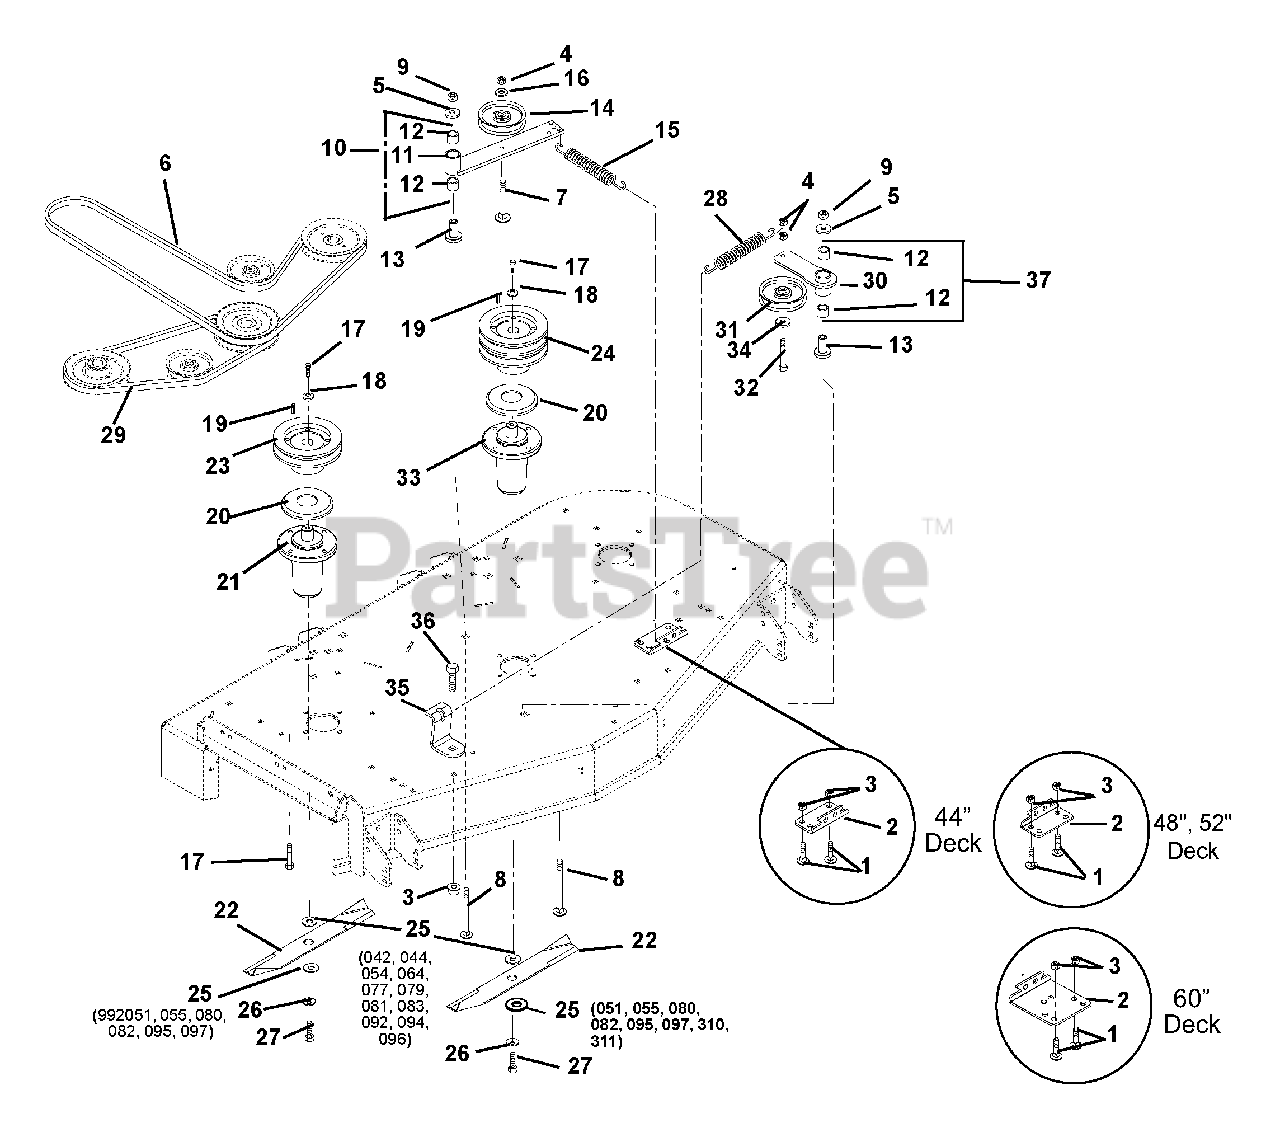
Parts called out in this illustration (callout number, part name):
1	Bolt, Round Head Square Neck .38-16 x .75 Grade 5
2	Bracket, Spring
3	Nut, Locking Top Flange .38-16
4	Nut, Locking Center .38-16
5	Washer, Flat Steel .531 x 1.25 x .10
6	V-Belt, B-Section 51.50 x .625
6	V-Belt, B-Section 55.75 x .625
6	V-Belt, B-Section 48.80 x .625
7	Bolt-Round Head Square Neck .38-16 x 2.75 Grade 5
8	Bolt, Round Head Square Neck .50-13 x 3.50 Grade 5
9	Nut, Locking Top Flange .50-13
10	Assembly, Idler Pivot Arm
11	Weldment, Idler Pivot Arm
12	Bearing, 1.00 x 1.12 x .75
13	Bearing, Pedestal Powdered Metal
14	Idler, Flat 4.00 x .38 (2.00 W)
15	Spring, Extension
16	Washer, Flat Steel .375 x 1.125 x .065
17	Bolt, Hex .38-16 x 1.00 EP30 Grade 8
18	Washer, Flat Steel .406 x 1.50 x .245
19	Key, Square .25 x .25 x 1.00 RC 40-50
20	Slinger, Dust
21	Assembly, Maintenance Free Spindle
22	Blade, Mower (18.00)
22	Blade, Mulching (18.00)
22	Blade, Mower 60"
22	Blade, Mower 60" Tungsten Mulch
22	Blade, Mower
22	Blade, 32" (16.25)
22	Blade, Mulching
23	Weldment, Spindle Sheave 5.00
23	Weldment, Spindle Sheave 6.00
24	Sheave, Double (5.25")
24	Sheave, Double (6.25")
25	Washer, Flat .64 x 1.81 x .250
26	Washer, Bellville .63 x 1.625 x .14
27	Bolt, Hex .62-18 x 1.75 Grade 8
28	Spring, Extension
29	V-Belt, B-Section 5L 49.75
29	V-Belt, B-Section 23.94 x .625
29	V-Belt, 5L-Section 49.97 x .672
30	Arm, Idler Pivot
31	V-Idler, 4.00 x .38
32	Bolt, Hex .38-16 x 2.25 Grade 5
33	Spindle Assembly (Center)
34	Washer, Flat Steel .406 x .812 x .065
35	Anchor, Spring
36	Bolt, Round Head Square Neck .38-16 x 1.00
37	Assembly, Idler Pivot Arm
